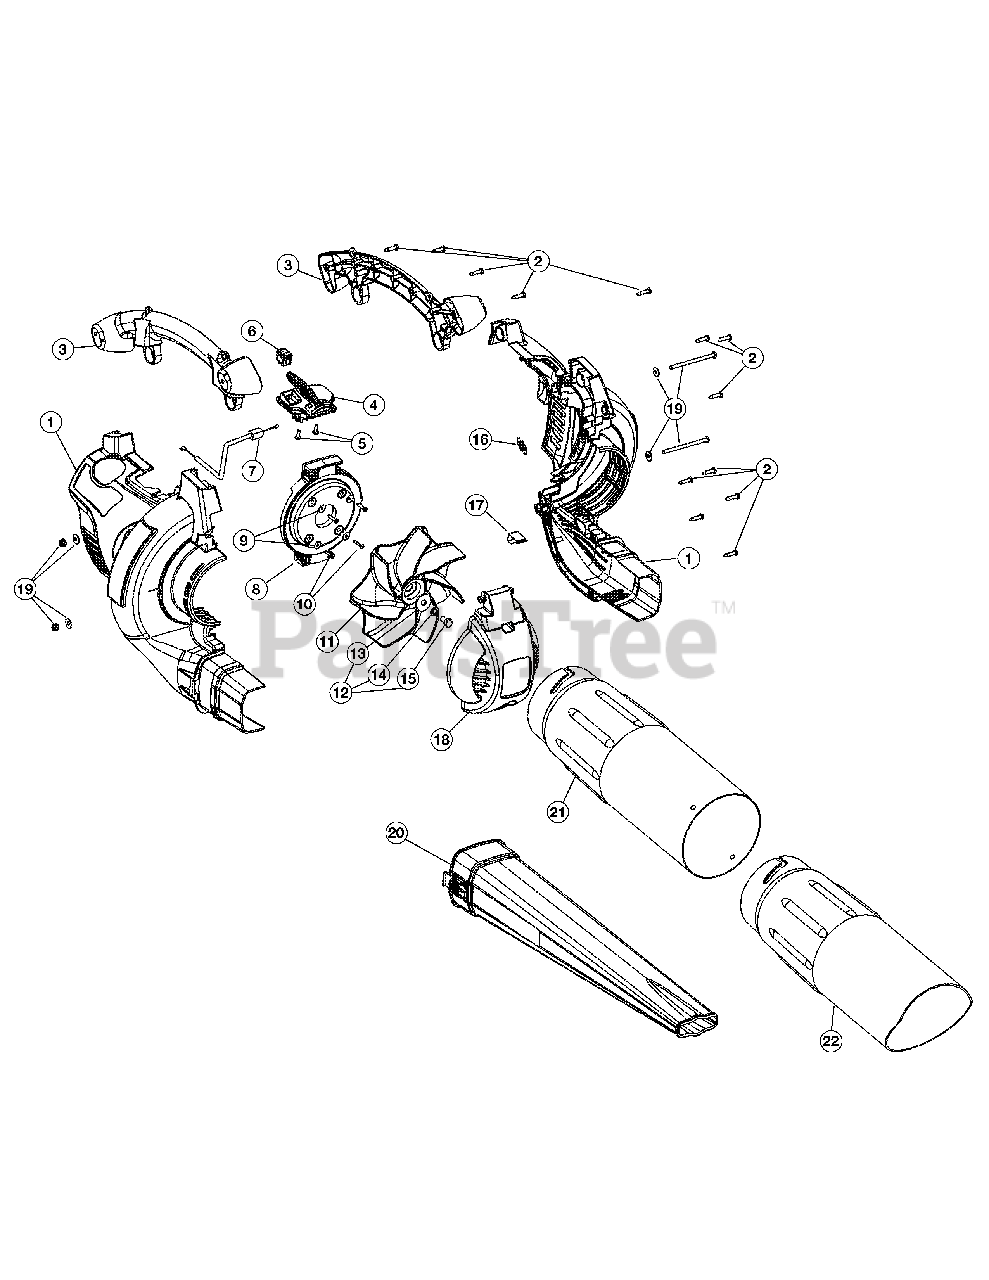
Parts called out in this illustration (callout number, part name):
1	Engine Cover Assembly
3	Handle Assembly
4	Throttle Control Assembly
6	Rocker Switch Assembly
7	Throttle Cable
8	Engine Mount Plate
11	Impeller Blade
12	Impeller Hardware
14	Lock Washer
16	Vacuum Door Spring
17	Vacuum Door Lock
18	Vacuum Door
19	Mounting Plate Hardware
20	Blower Tube
21	Upper Vacuum Tube
22	Lower Vacuum Tube
